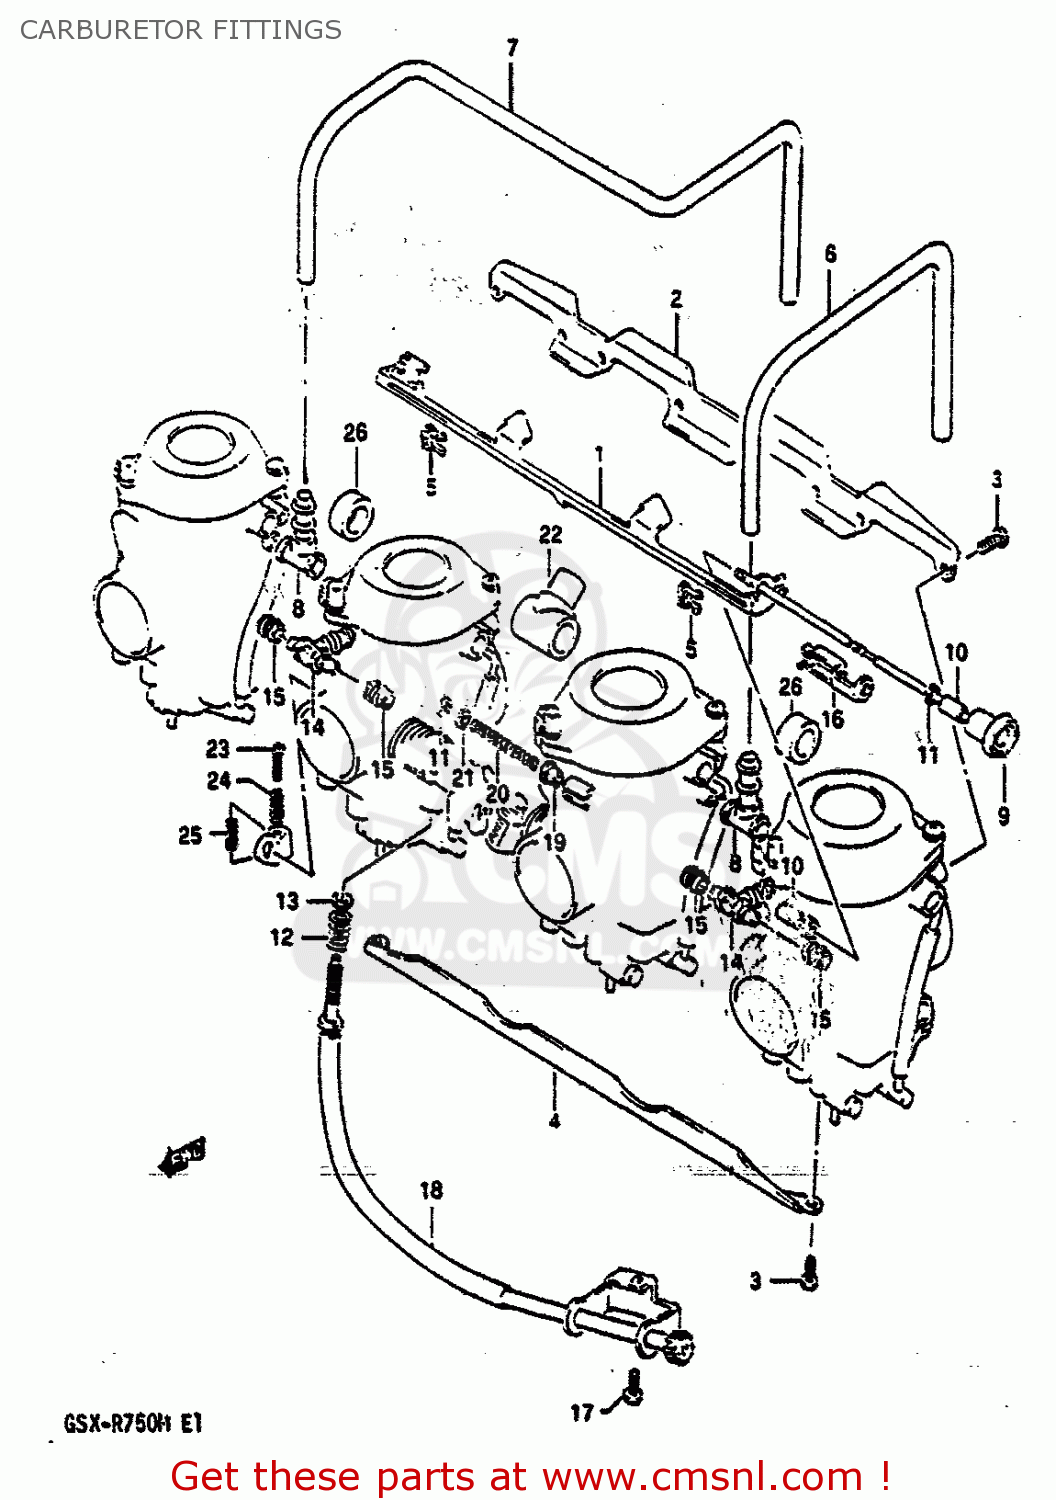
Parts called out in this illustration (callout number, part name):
1	LEVER
2	PLATE
3	SCREW
4	PLATE
5	HOLDER
6	HOSE
7	HOSE
8	HOSE
9	SHAFT ASSY,STARTER
10	SPACER
11	E RING
12	SPRING
13	WASHER
14	NIPPLE
15	SEAL
16	PLATE
17	SCREW
18	ADJUSTER
19	RING
20	SPRING
21	WASHER
22	HOSE ASSEMBLY
23	SCREW
24	SPRING
25	SPRING
26	HOSE
